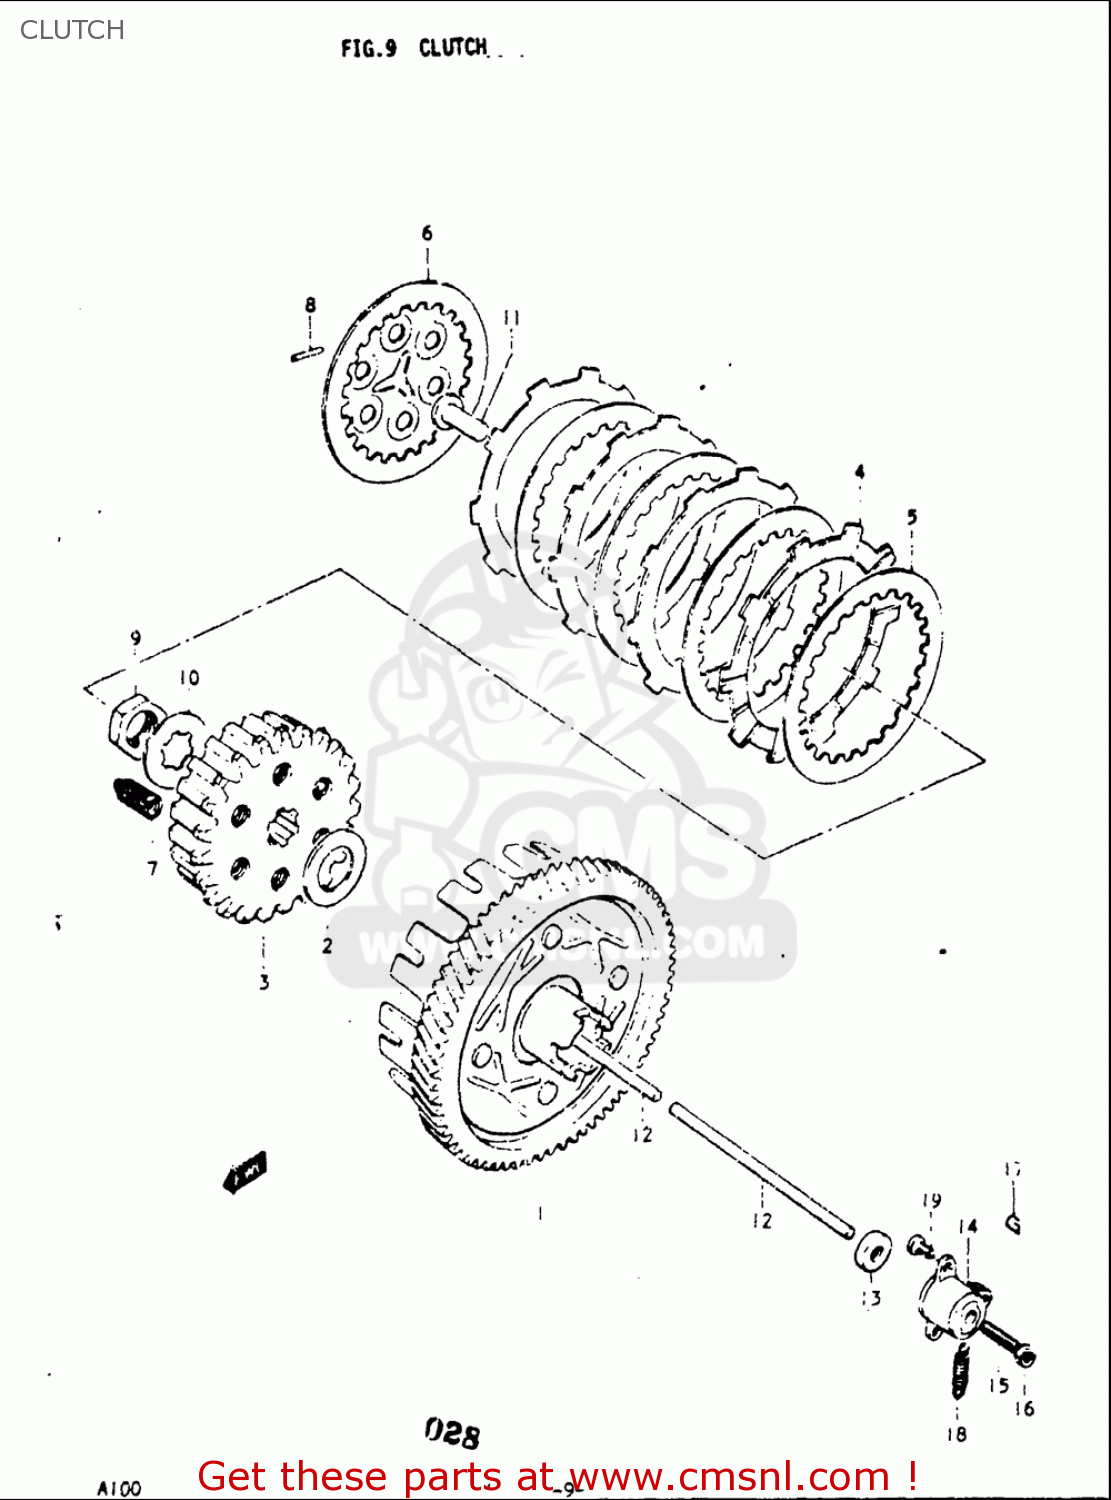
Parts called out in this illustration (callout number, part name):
1	GEAR ASSEMBLY,PRIMARY
2	WASHER
3	HUB,CLUTCH SLEEVE
4	PLATE,CLUTCH DRIVE (NAS)
5	PLATE,CLUTCH DRIVEN (NAS)
6	PLATE,CLUTCH PRESSURE
7	SPRING
8	PIN(2.5X19.8)
9	NUT
10	WASHER,LOCK
12	ROD,CLUTCH PUSH
13	SEAL,OIL(5.5X16X8)
14	SCREW ASSY,CLUTCH RELEASE
15	SCREW(6X25)
16	NUT
17	PIECE,RELEASE ARM END
18	SPRING
19	SCREW(5X12)
